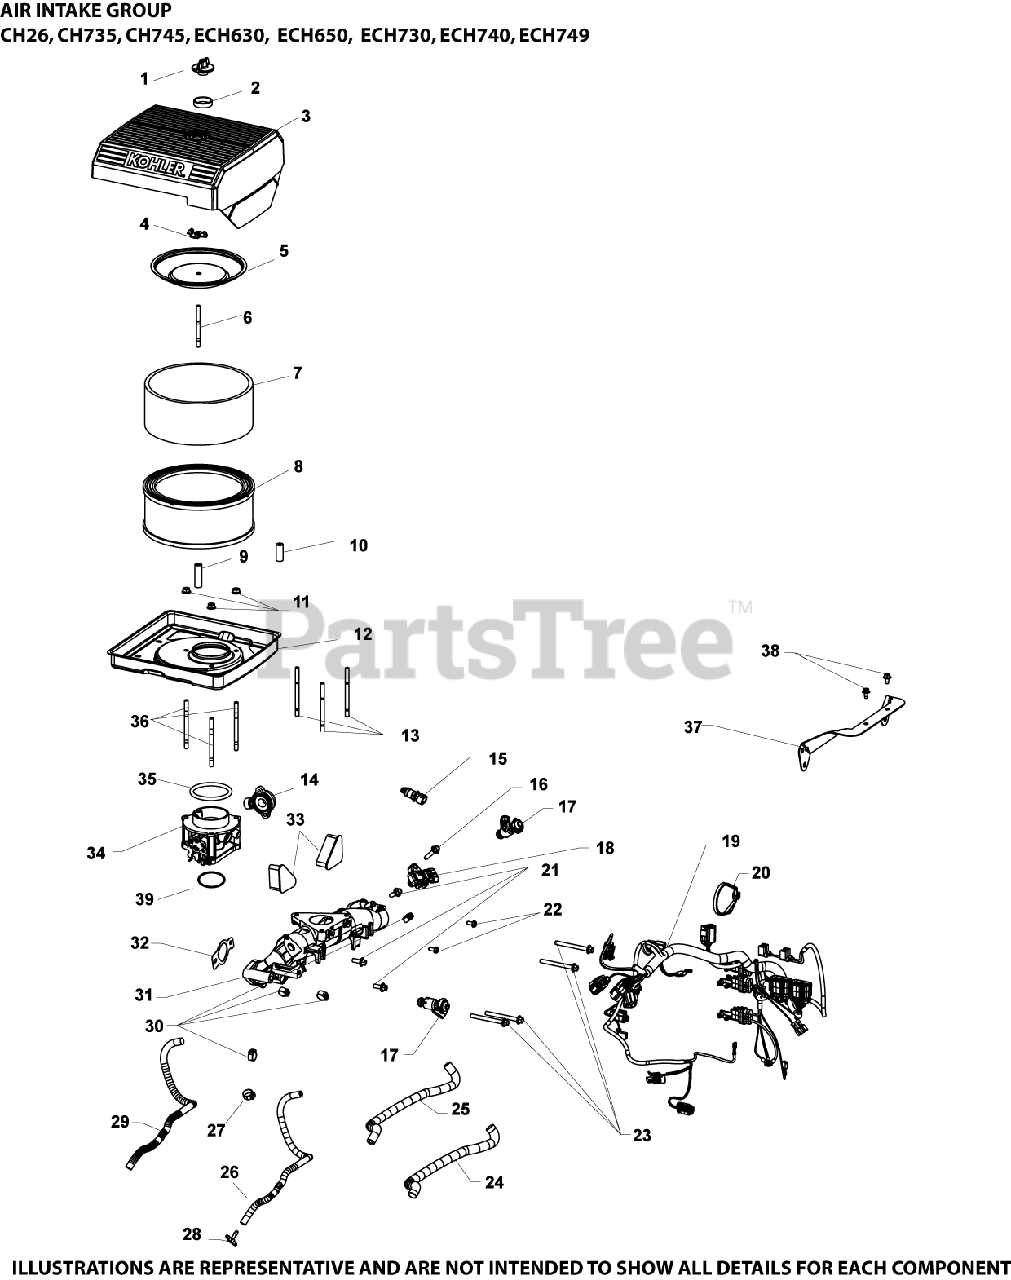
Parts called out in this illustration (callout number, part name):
1	KNOB, COVER
3	COVER, AIR CLEANER
4	NUT, WING
5	COVER, INNER AIR CLEANER
6	STUD, LOW PROFILE A/C
7	PRE-CLEANER (HIGH)
8	ELEMENT, AIR FILTER (HIGH) - Also available Retail Packaged 24 883 03-S1 Air Filter Kit
12	BASE, AIR CLEANER
13	STUD,M6X1.0X84
15	SENSOR, AIR TEMPERATURE
16	SCREW, FLG M6X1.0X25
17	INJECTOR, FUEL
18	SENSOR, MAP
19	HARNESS, WIRING ASSEMBLY
21	SCREW, FLG M6X1.0X16
22	SCREW, WSH HD TAP #8-18X1/2"
23	SCREW, FLG M6X1.0X60
24	SLEEVE, FUEL LINE
25	HOSE, FUEL LOW PERMEATION-DISC.
26	HOSE, EVAPORATIVE (15.0)
27	CLAMP, FUEL HOSE
28	CONNECTOR, TEE - USE 25 155 56-S
29	SLEEVE, ANTI-ABRASION
30	CLAMP, OETIKER
31	KIT, MANIFOLD
32	GASKET, INTAKE MANIFOLD USE 24 041 79-S
33	COVER, BLOWER HOUSING USE 24 096 160-S
34	BODY, THROTTLE ASSEMBLY-USE 25 583 10-S
35	O-RING, AIR CLEANER BASE
37	BRACKET, AIR CLEANER BASE
38	SCREW, FLG THD FRM M5X.8X10
39	O-RING, THROTTLE BODY
